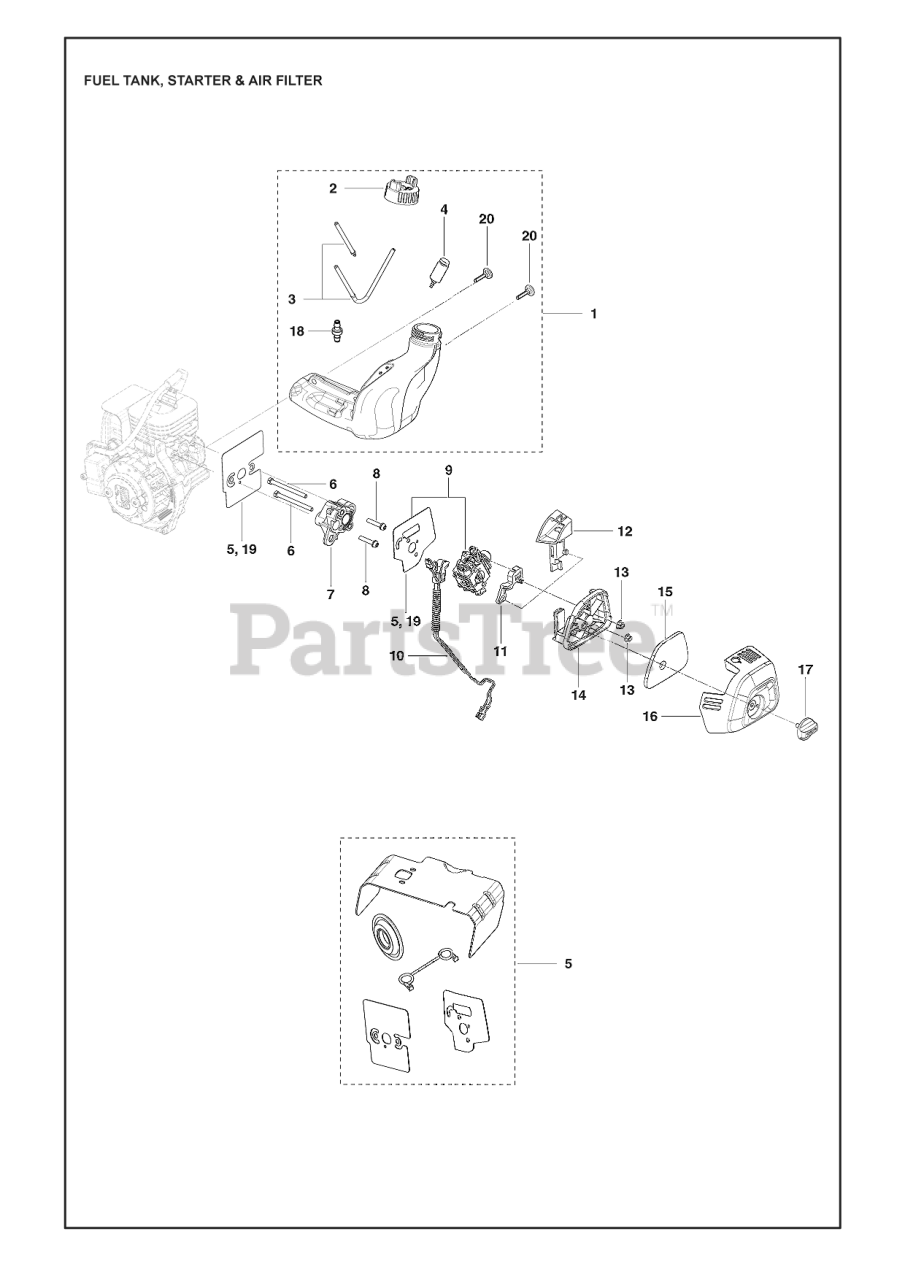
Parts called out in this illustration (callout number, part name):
1	SERVICE KIT 130 TRIMMER FUEL
3	SERVICE KIT 130 TRIMMER HOSE
4	ASSY FUEL PICKUP PRE FLUSHED
5	GASKET KIT
6	BOLT CARB ADAPTOR
7	CARB ADAPTOR
8	SCREW-M5-0.8 X 25MM(TAP)
9	SERVICE KIT 130 TRIMMER CARBU
10	ASSY CABLE / WIRE HARNESS
11	CHOKE CONTROL 130 TRIMMER BUTT
12	CHOKE LEVER 130 TRIMMER BUTTER
14	AIR FILTER HOLDER 130 TRIMMER
15	GSPH Elements
16	FILTER COVER 130 TRIMMER
17	KNOB CLEANER COLOR:GREY
18	FUEL LINE FITTING
19	SERVICE KIT 130 TRIMMER GASKET
20	SCREW FUEL TANK RETAINER
